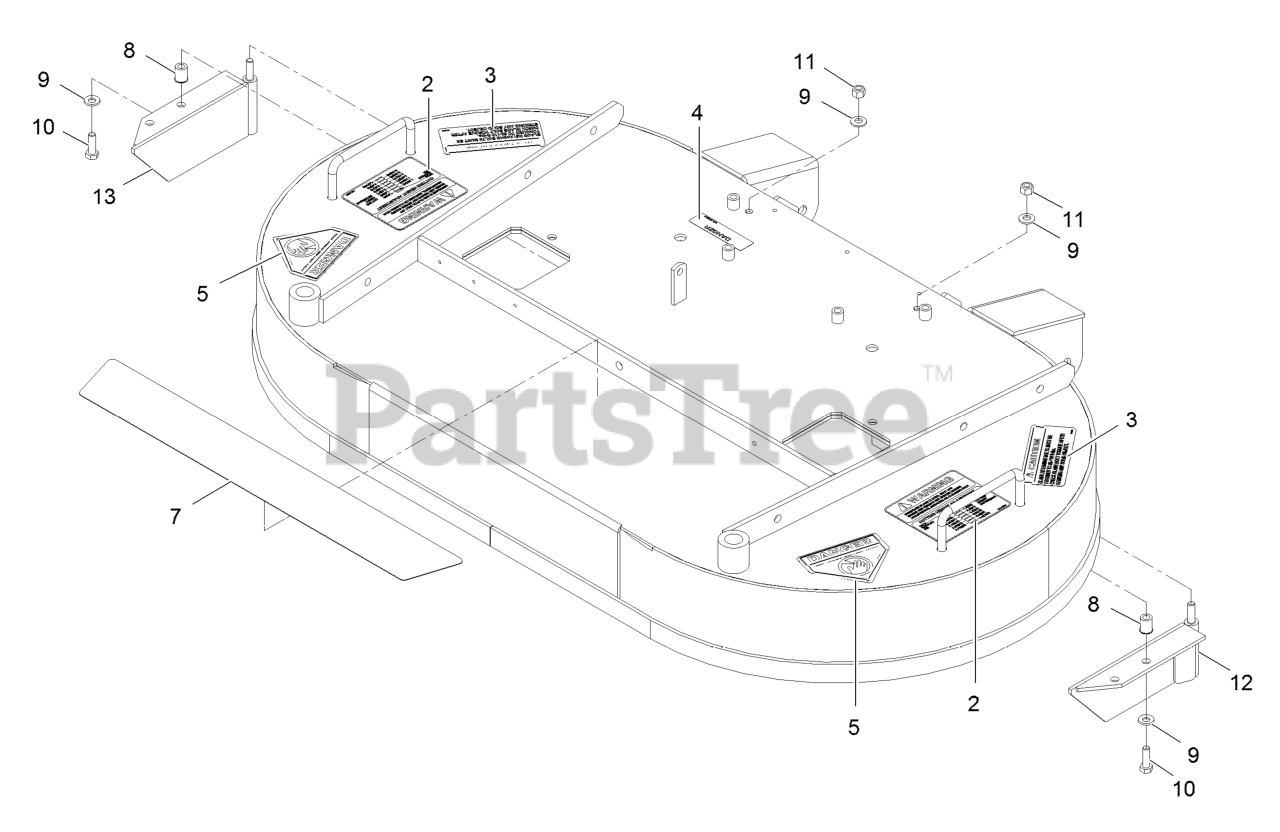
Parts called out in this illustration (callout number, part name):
3	DECAL-TORQUE
4	DECAL-COVER, MISSING
5	DECAL-DANGER
7	PAD-SKID, ANTI
8	NUT-CLINCH
9	WASHER-SPRING
10	SCREW-HH
11	NUT-LOCK, NI
12	BAFFLE-LH
13	BAFFLE-RH
